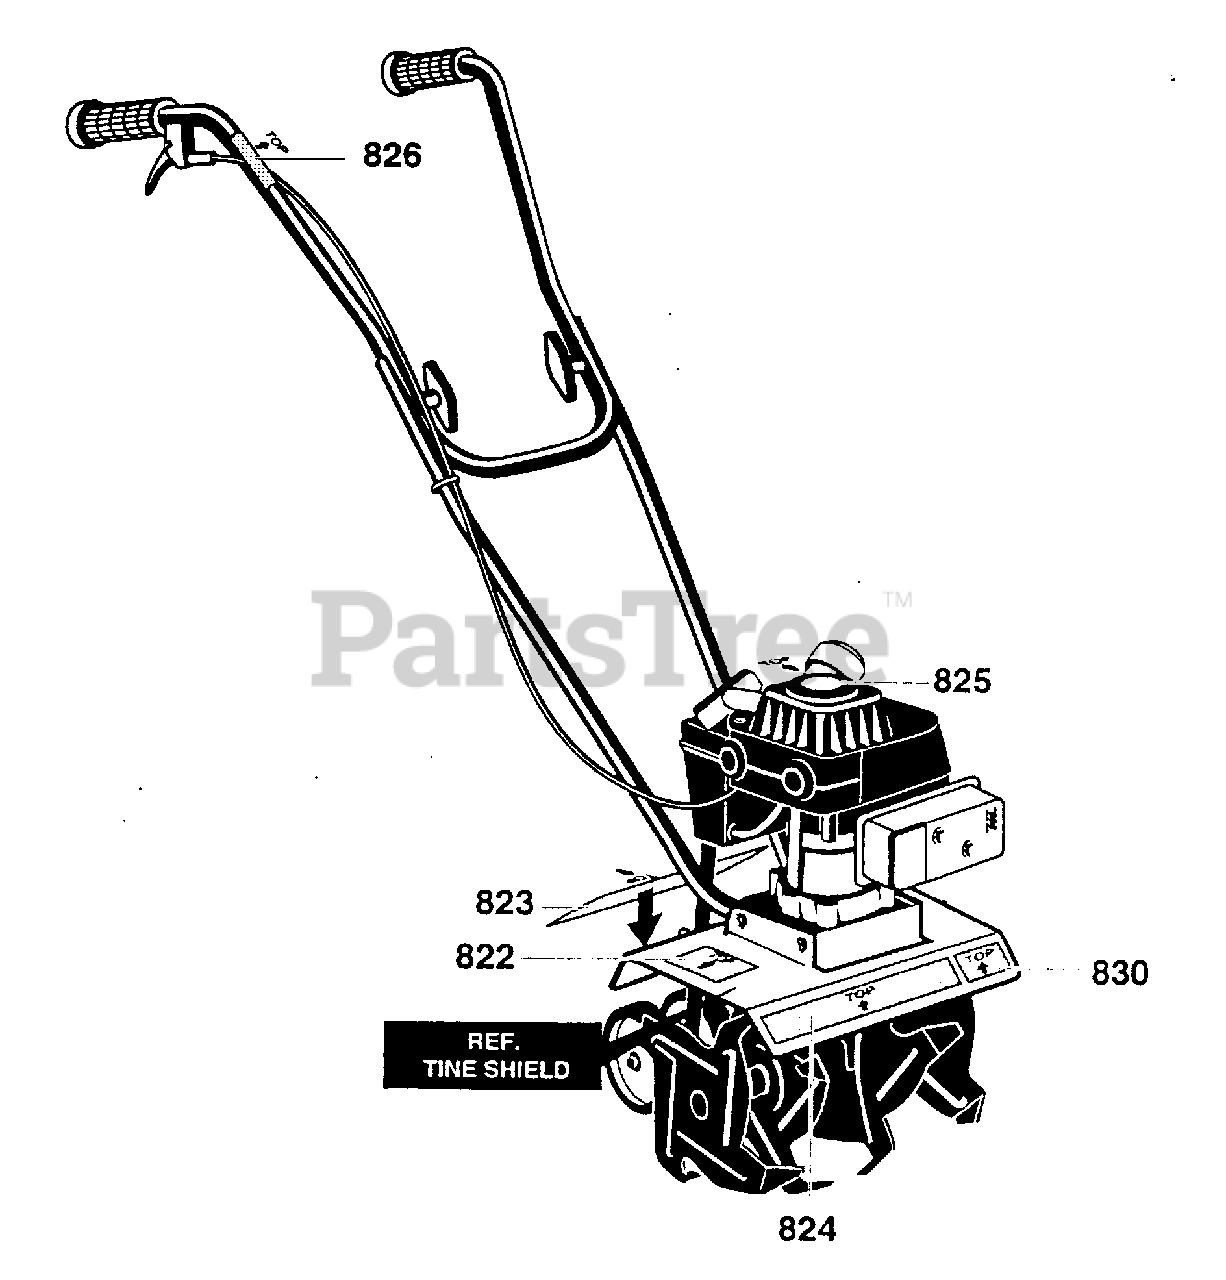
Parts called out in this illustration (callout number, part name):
822	REFERENCE ONLY
823	DECAL, CAUTION
824	DECAL, HUSQVARNA TOP COVER
825	DECAL, RECOIL HSING HUSQV.
826	DECAL, HOLD RH GRIP
830	DECAL, TINE SHIELD CT-20 HUSQV
